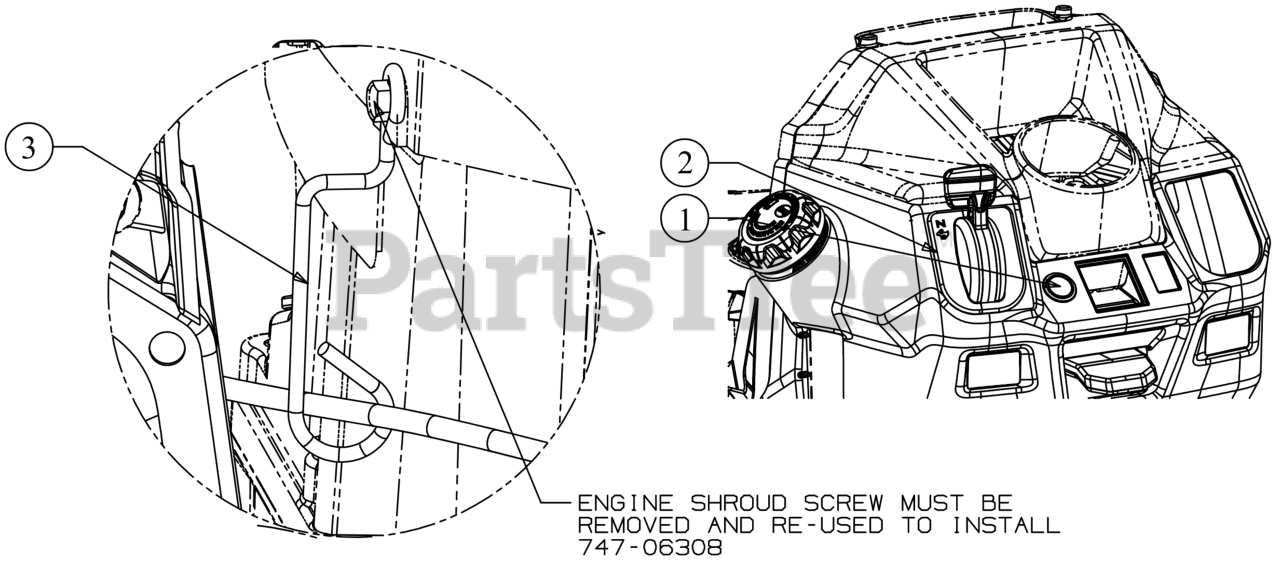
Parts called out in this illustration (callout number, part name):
1	CHOKE PLUG
2	THROTTLE/CHOKE CABLE 43.5x1.7
3	CABLE GUIDE WIRE
